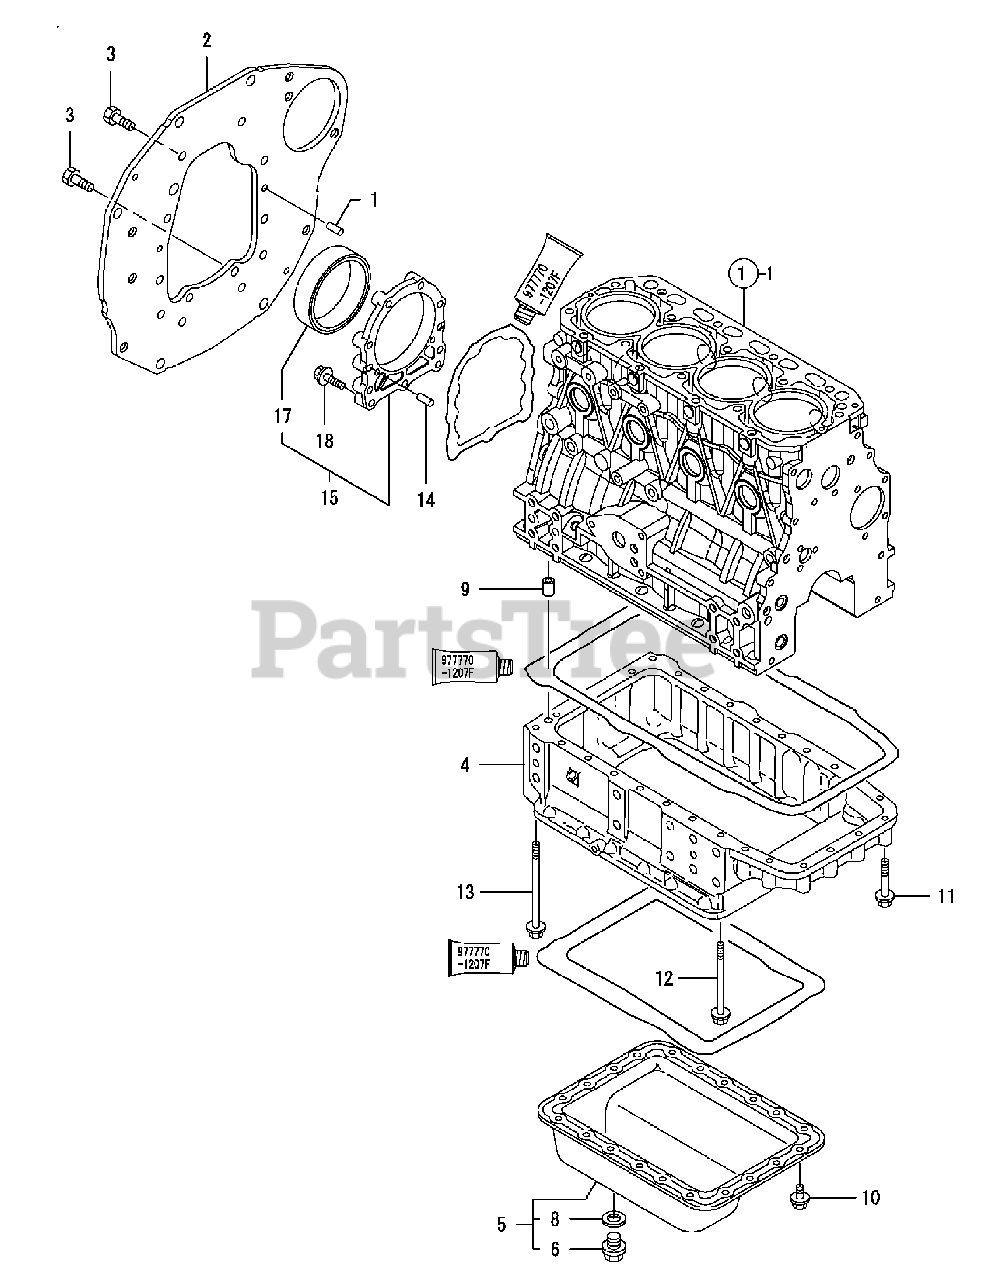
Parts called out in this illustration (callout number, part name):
1	PARALLEL PIN, M8X16
2	FLANGE, MOUNTING
5	COVER ASSY, OIL SUMP
10	BOLT M 8X 12 PLATED
11	BOLT M 8X 50 PLATED
12	BOLT M 8X100 PLATED
13	BOLT M 8X120 PLATED
14	PARALLEL PIN, M8X16
15	CASE ASSY, OIL SEAL
